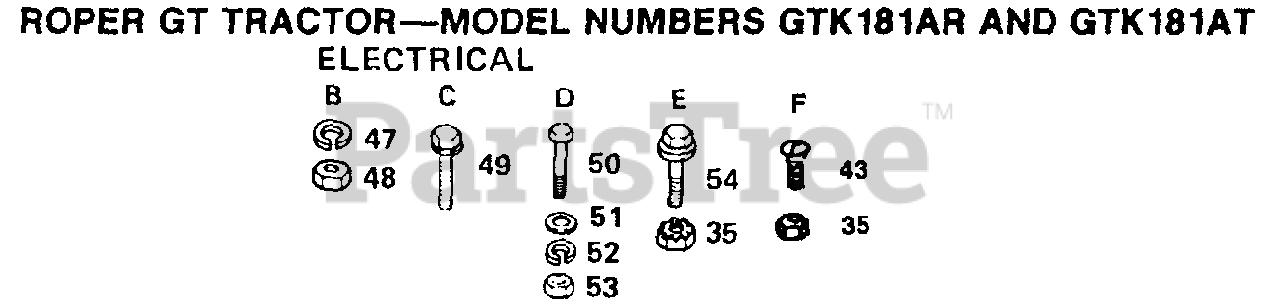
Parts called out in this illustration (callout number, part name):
35	"NUT,KEPS"
48	NUT
49	SCREW ST
50	BOLT LT
51	WASHER
52	LOCKWASHER
54	SCREW
